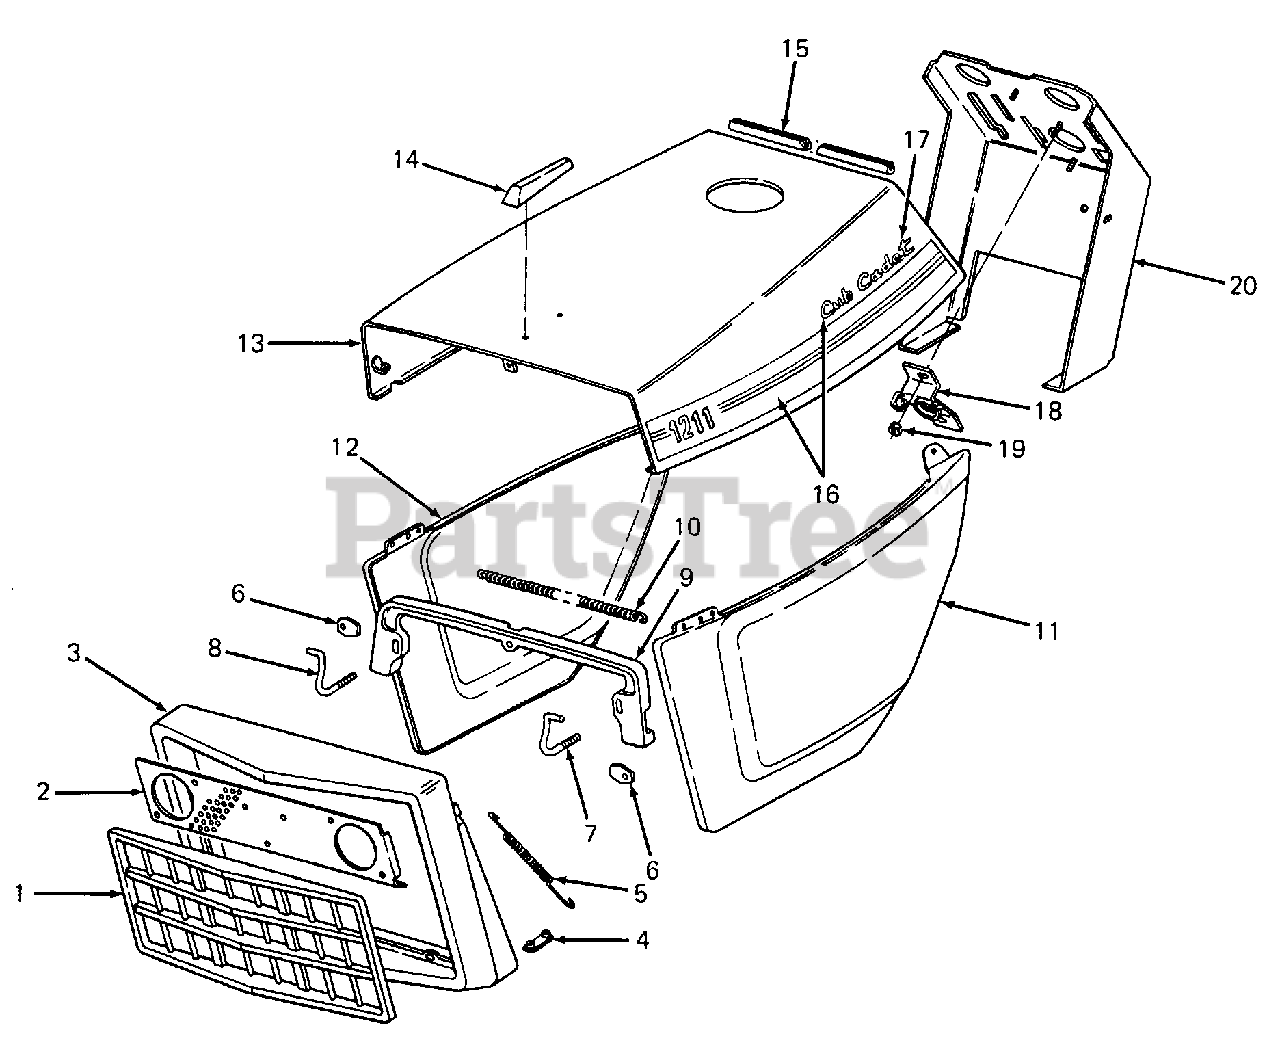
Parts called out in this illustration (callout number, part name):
1	Grille, Insert
4	Retainer, Grille Housing
5	Spring
6	Plate, Hood Hinge
7	Hinge, LH - Hood
8	Hinge, RH - Hood
9	Support, Hood
10	Spring, Side Panel
11	Panel, LH - Side
12	Panel, RH - Side
14	Ornament, Hood
15	Seal, Edge
16	Kit - Hood Label
17	Graphic, Cub Cadet Script w/Adhesive
18	Support, Steering Column
19	Nut, Hex Insert Lock, 1/4-20
